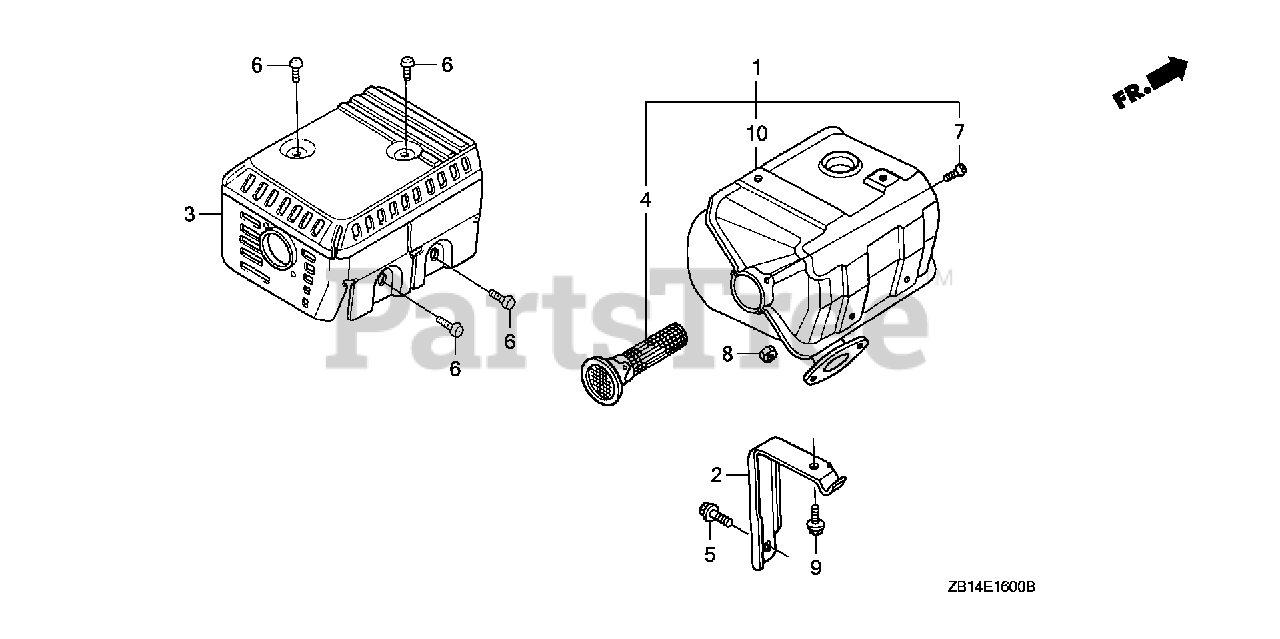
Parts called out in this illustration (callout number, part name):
2	STAY, MUFFLER
3	PROTECTOR, MUFFLER (SILENT)
4	ARRESTER, SPARK (SILENT)
5	BOLT, FLANGE (6X13) (CT200)
6	SCREW, TAPPING (5X8)
7	SCREW, TAPPING (4X6)
8	NUT, HEX. (8MM)
9	BOLT, FLANGE (6X12)
10	MUFFLER (SILENT)
